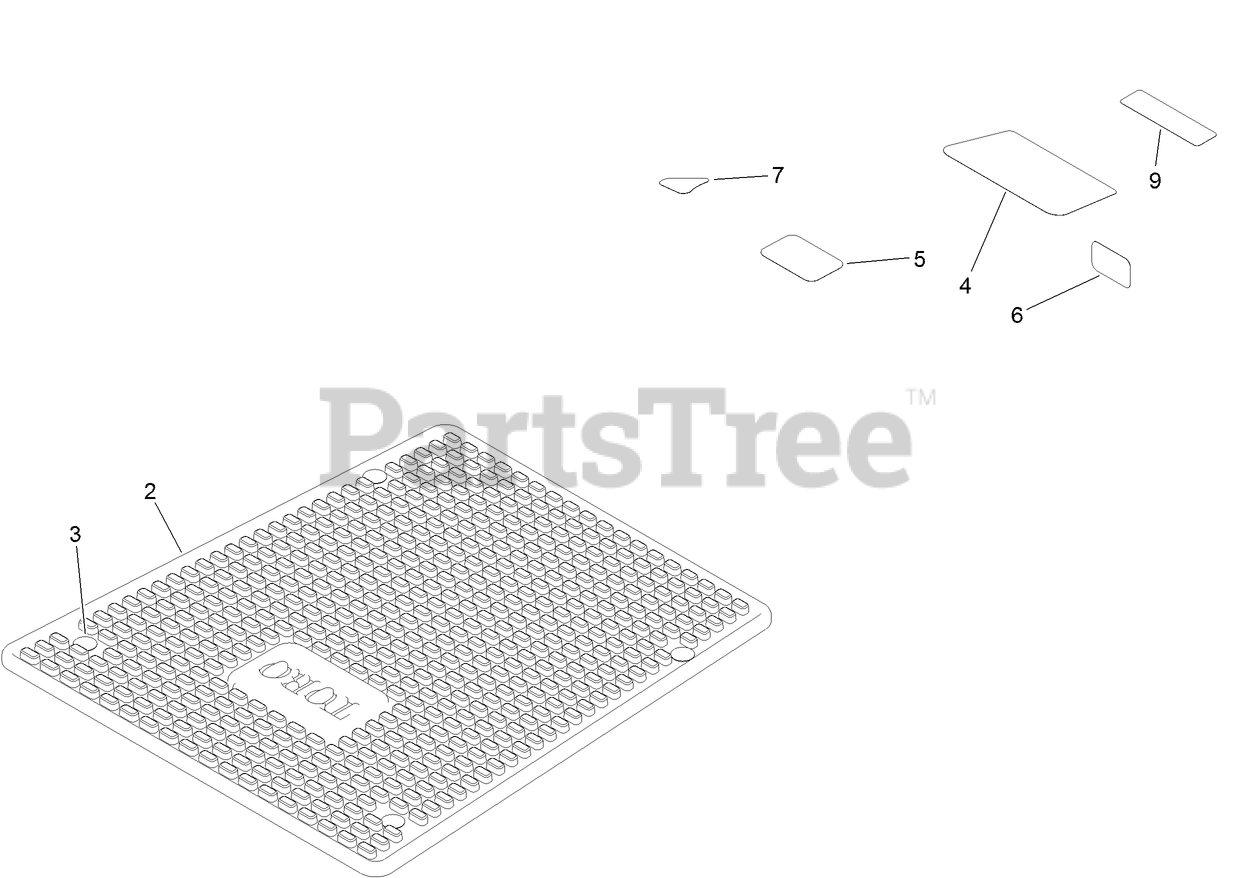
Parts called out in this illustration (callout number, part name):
2	MAT-FLOOR
3	PLUG-PLASTIC
4	DECAL-ENGINE
6	PLACARD-INTAKE
7	DECAL-DRAIN, OIL
9	DECAL-BUCKET
